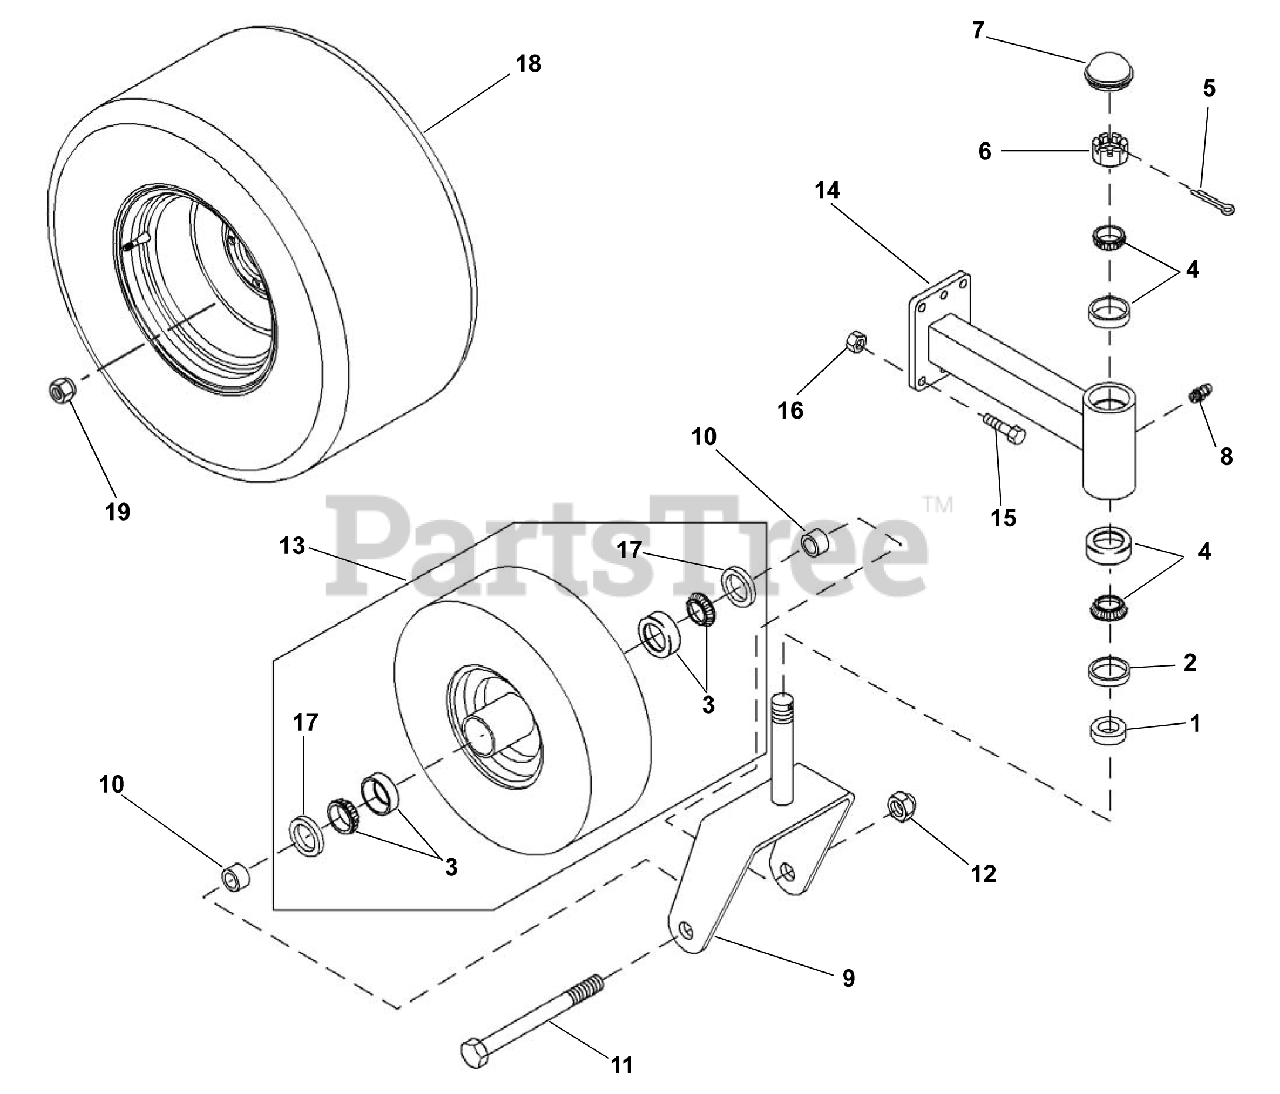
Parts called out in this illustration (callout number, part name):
1	SPACER, CASTER BUSHING
2	SEAL, WHEEL BEARING
3	BEARING ASSEMBLY, CASTER WHL C
4	SPINDLE BEARING KIT, CUP & CNE
5	PIN,COTTER,DIN94,3.2X50-ST-ZN
6	NUT HEX SLOTTED 1-14 G5 ZC
7	CAP, DUST
8	FITTING, LUBRICATION
9	YOKE
10	SPACER, CASTER WHEEL
11	BLT-HEX M6X1.0X12 YZ EP30
12	NUT-JAM .31-24 YWZC
13	CASTER WHEEL AND TIRE ASSEMBLY
14	CASTER ARM
15	BLT-HEX M10 X 1.5X25 YWZC
16	NUT-LK-NYL M10-1.5 YWZC
17	SEAL
18	WHEEL & TIRE ASMBLY, REAR 48"D
19	NUT-LUG .50-20 YWZC
